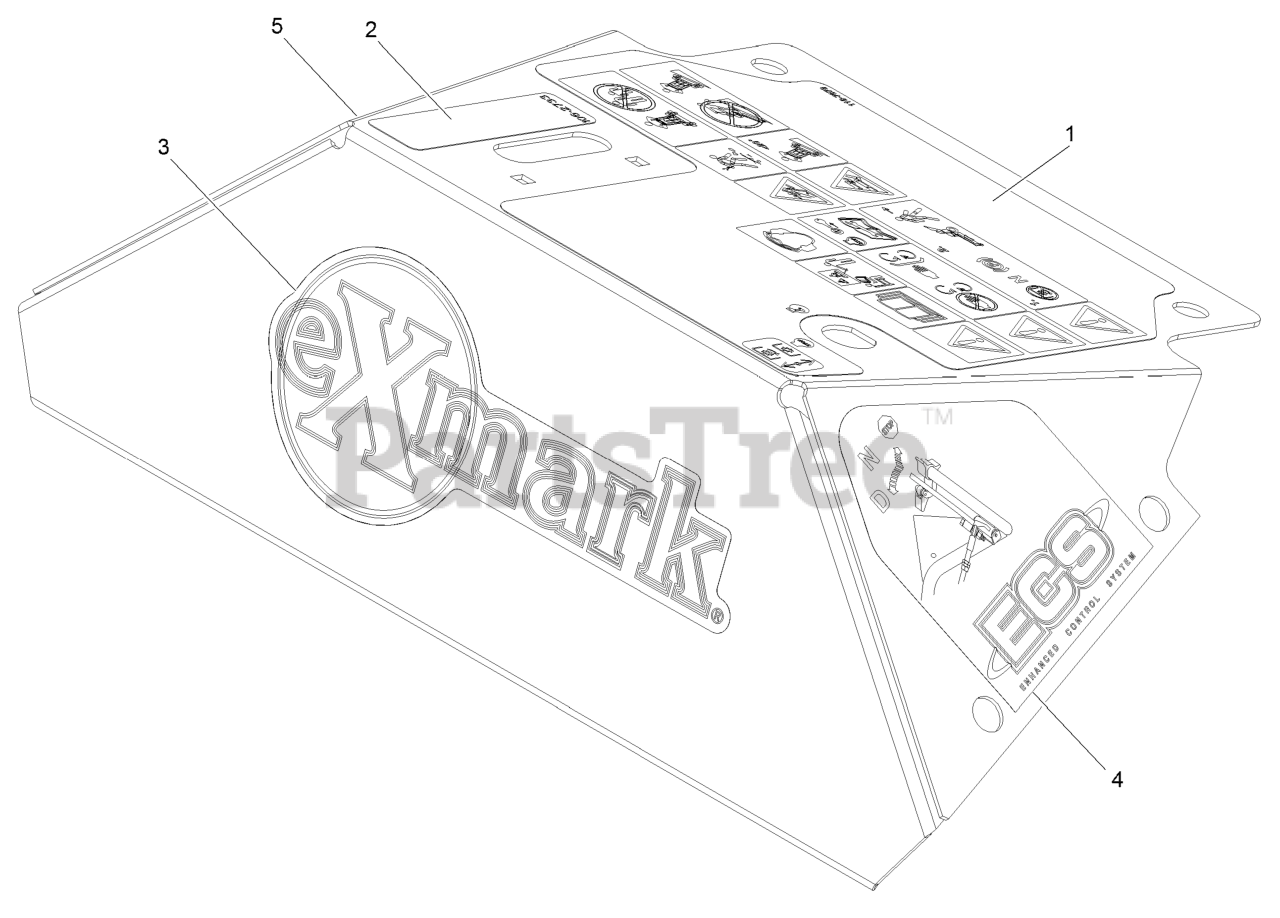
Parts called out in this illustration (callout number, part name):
1	DECAL-CONSOLE METRO ECS
2	DECAL-THROTTLE
3	DECAL, EXMARK LOGO
4	DECAL,LH ECS INSTRUCTION
5	DECAL,RH ECS INSTRUCTION
